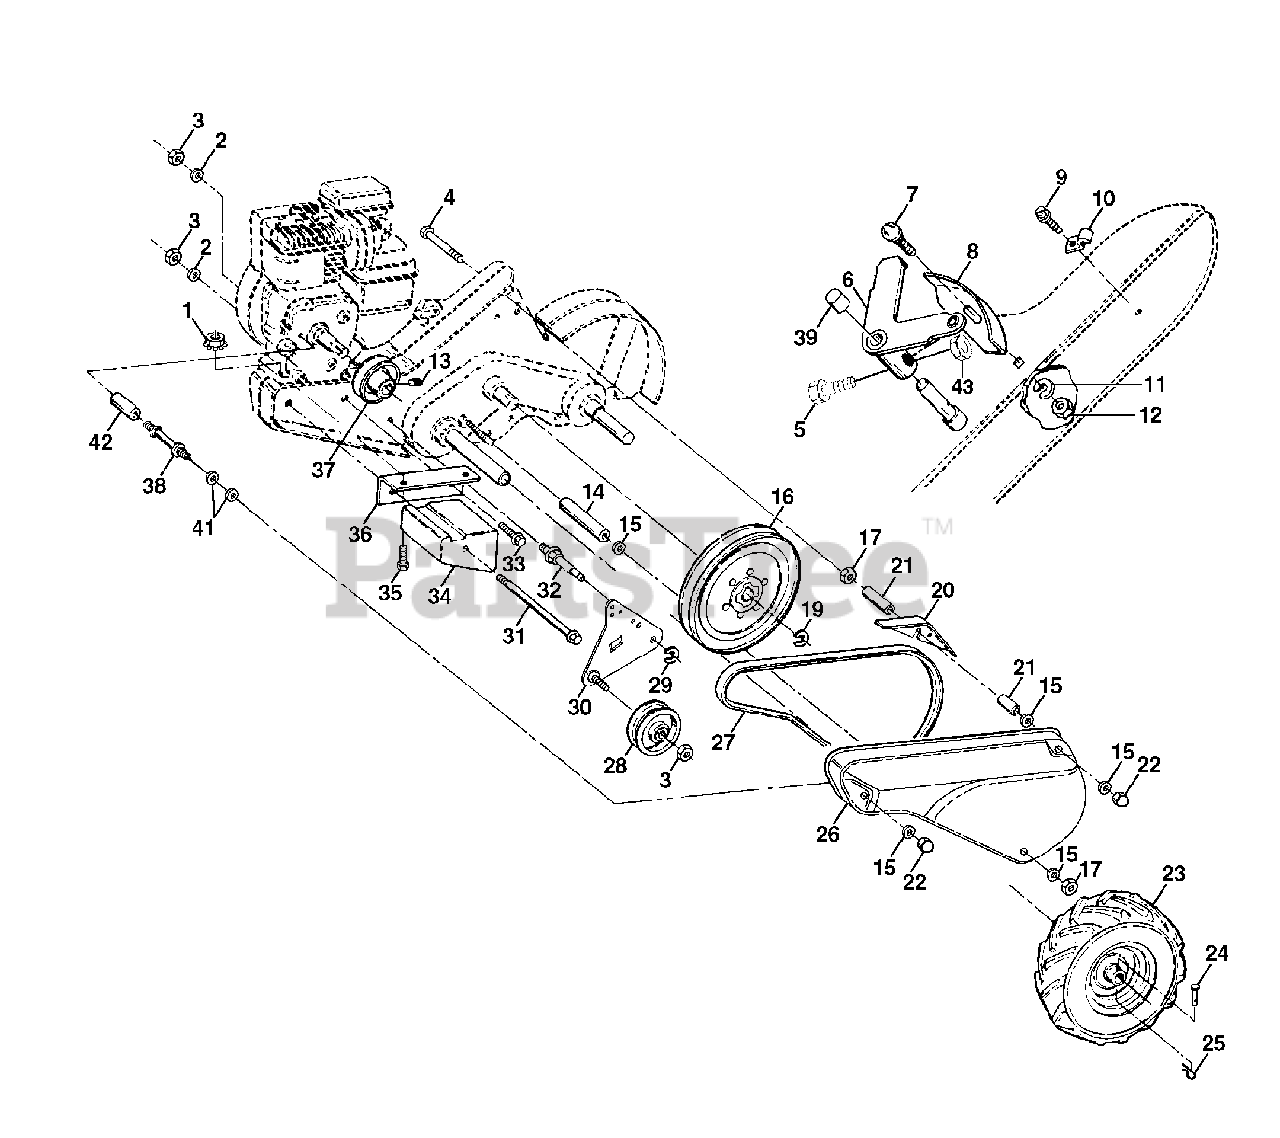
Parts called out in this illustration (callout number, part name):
1	Nut, Keps 5/16-18
2	Washer, Lock 3/8
3	Nut, Hex 3/8-16
4	Bolt, Hex 5/16-18 x 4-1/4
5	Screw, Shift Lever
6	Lever, Shift
7	Bolt, Carriage 1/4-20 x 1/2 Gr. 5
8	Plate, Shift Indicator
9	Screw, Hex, Washer Head, Slotted #10-24 x 1/2
11	Washer, Lock 1/4
12	Nut, Hex 1/4-20
13	Screw, Set, Hex 5/16-18 x 3/8
14	Spacer, Split 0.327 x 0.42 x 2.68
15	Washer 11/32 x 11/16 x 16 Ga.
16	Sheave, Transmission
17	Nut, Hex 5/16-18
19	Retainer, Ring
20	Guard, Pinch Point
21	Spacer, Split 0.327 x 0.42 x 1.688
22	Nut, Cap 5/16-18
23	Rim
23	Tire Valve
24	Rivet, Drilled
25	Clip, Hairpin
26	Guard, Belt
27	Belt, V
28	Pulley, Idler
29	Ring, Klip
30	Bracket, Idler
31	Bolt, Hex 5/16-16 x 12
32	Shaft, Idler Arm
33	Bolt, Hex 3/8-16 x 1
34	Counterweight, L. H.
35	Bolt, Hex 5/16-18 x 2
36	Bracket, Reinforcement, L. H.
37	Sheave, Engine
38	Stud, Belt Guard
39	Cap, Plunger Blk
41	Washer 11/32 x 1 x 10 Ga.
43	Nut, Lock #10-24
